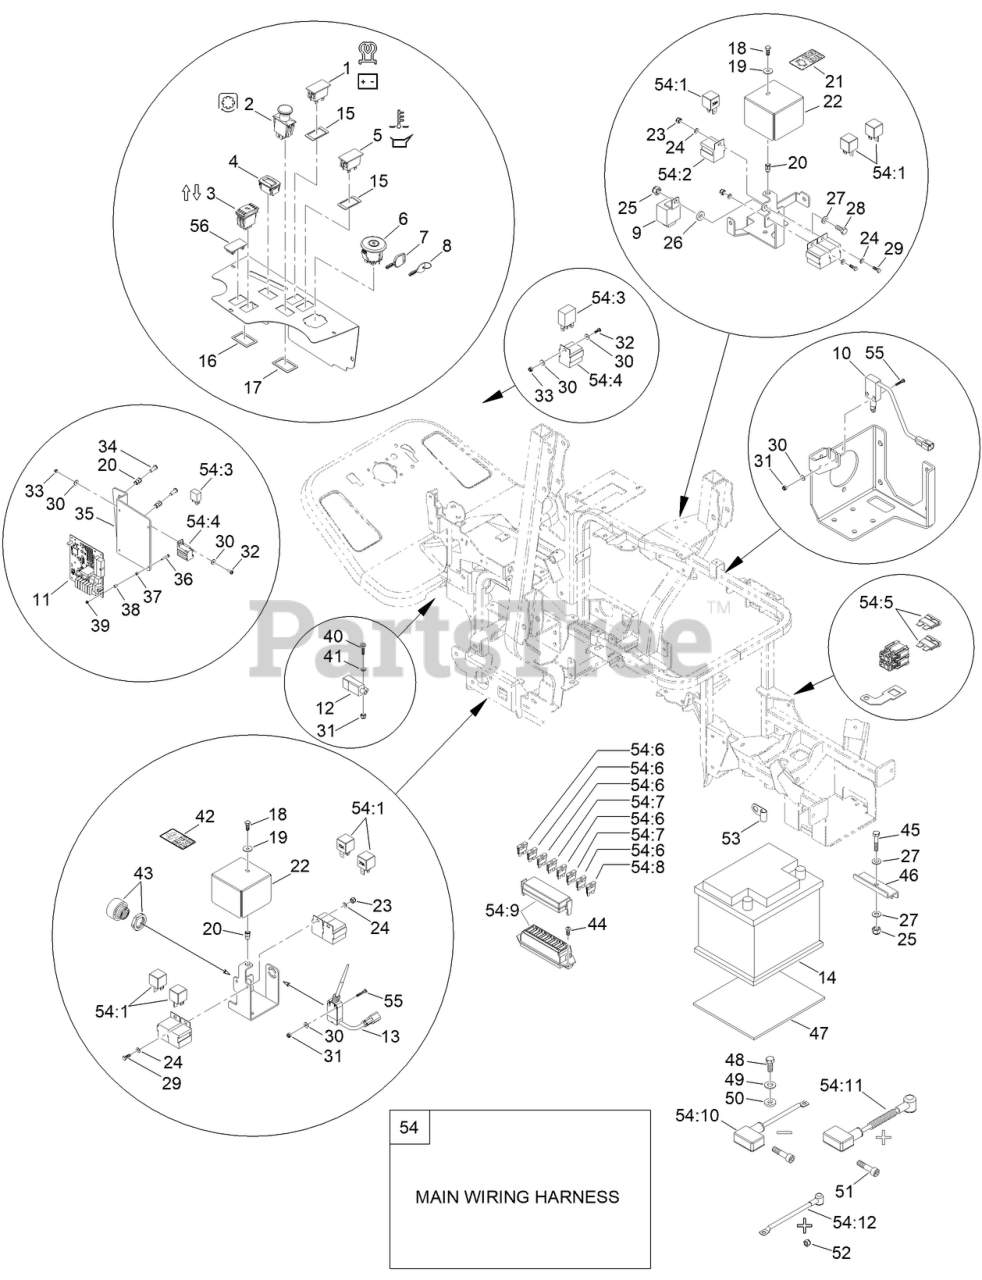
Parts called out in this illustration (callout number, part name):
1	LIGHT-INDICATOR, GLOW/BATTERY
2	SWITCH-PTO
3	SWITCH, HOC
4	HOUR METER
5	LAMP, OIL/WATER
6	SWITCH, KEY
7	KEY-IGNITION, METAL
8	KEY-IGNITION, PLASTIC COVER
9	TIMER, KUBOTA
10	MICROSWITCH, NEUTRAL
11	ELECTRIC BOARD, MACHINE
12	MICROSWITCH, PARKING BRAKE
13	MICROSWITCH, LIFTED HOPPER
14	BATTERY
15	GASKET
16	FRAME, HOUR METER
17	RETAINER-SWITCH
19	WASHER
20	INSERT-THREADED
21	DECAL-ENGINE RELAY
22	COVER, RELAYS
24	WASHER
26	WASHER
27	WASHER
29	SCREW-HH CAP
30	WASHER
32	SCREW-PAN
35	SUPPORT, ELECTRIC BOARD
38	BUSHING-NYLON
41	WASHER
42	DECAL-RELAY FAN
43	BUZZER
46	BRACKET-CLAMP, BATTERY
47	BUSHING-PLASTIC
49	WASHER
50	WASHER
53	GROMMET
54	MAIN WIRING HARNESS, PLH600
54:2	BASE-RELAY 70A
54:4	BASE-RELAY, MINATURE
54:5	FUSE-40A
54:6	FUSE 15A
54:7	FUSE 5A
54:8	FUSE-BLADE, 3 AMP
54:9	BOX-FUSE
54:10	CABLE, BATTERY NEGATIVE
54:11	CABLE, BATTERY POSITIVE
54:12	CABLE, ALTERNATOR
56	PLUG, SWITCH
